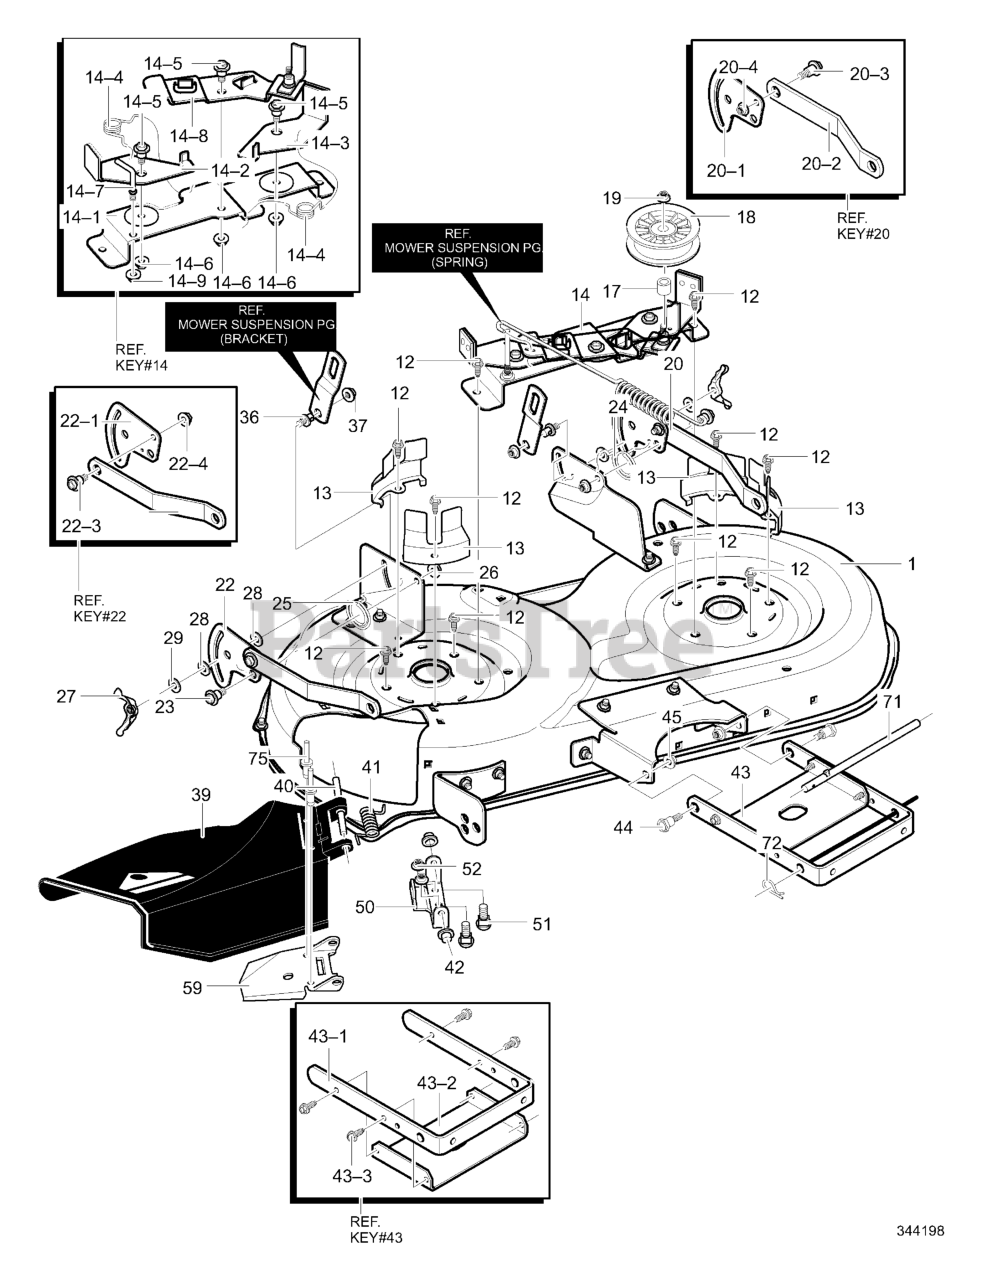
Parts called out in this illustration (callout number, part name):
1	ASSEMBLY, BLADE HOUSING
12	BOLT-3/8 X 1.25
13	COVER, BELT GUIDE
14	ASSEMBLY, IDLER BRACKET
14-1	BRACKET, BRAKE
14-2	ASSEMBLY, RIGHT BRAKE
14-3	ASSEMBLY, LEFT BRAKE
14-4	SPRING, TORSION
14-5	BOLT
14-6	NUT
14-7	SCREW, GUIDE
14-8	ASSEMBLY, IDLER ARM
14-9	NUT
17	SPACER 1/2 TO 17MM
18	PULLEY, IDLER
19	NUT, 3/8-16
20	ASSEMBLY, LEFT LIFTER
20-1	PLATE, SUSPENSION
20-2	BRACKET, SUSPENSION
20-3	BOLT, SHOULDER
20-4	NUT, FLANGE
22	ASSEMBLY, RIGHT LIFTER
22-1	PLATE, SUSPENSION
22-2	BRACKET, SUSPENSION
22-3	BOLT, SHOULDER
22-4	NUT, FLANGE
23	BOLT, SHOULDER
24	SPRING, TORSION
25	SPRING, TORSION
27	WINGNUT
28	PAD, FRICTION
29	WASHER
36	PIN, HANGER
39	DEFLECTOR, CHUTE
40	ROD, CHUTE DEFLECTOR
41	SPRING, TORSION
42	NUT, PUSH CAP
43	ASSEMBLY, STIFFENER
43-1	BRACKET, SUSPENSION
43-2	STIFFENER, DECK
44	BOLT, SHOULDER
50	BRACKET, CHUTE
51	BOLT, CARRIAGE
59	SUPPORT, DEFLECTOR
71	ROD, HANGER
72	PIN, HAIR
